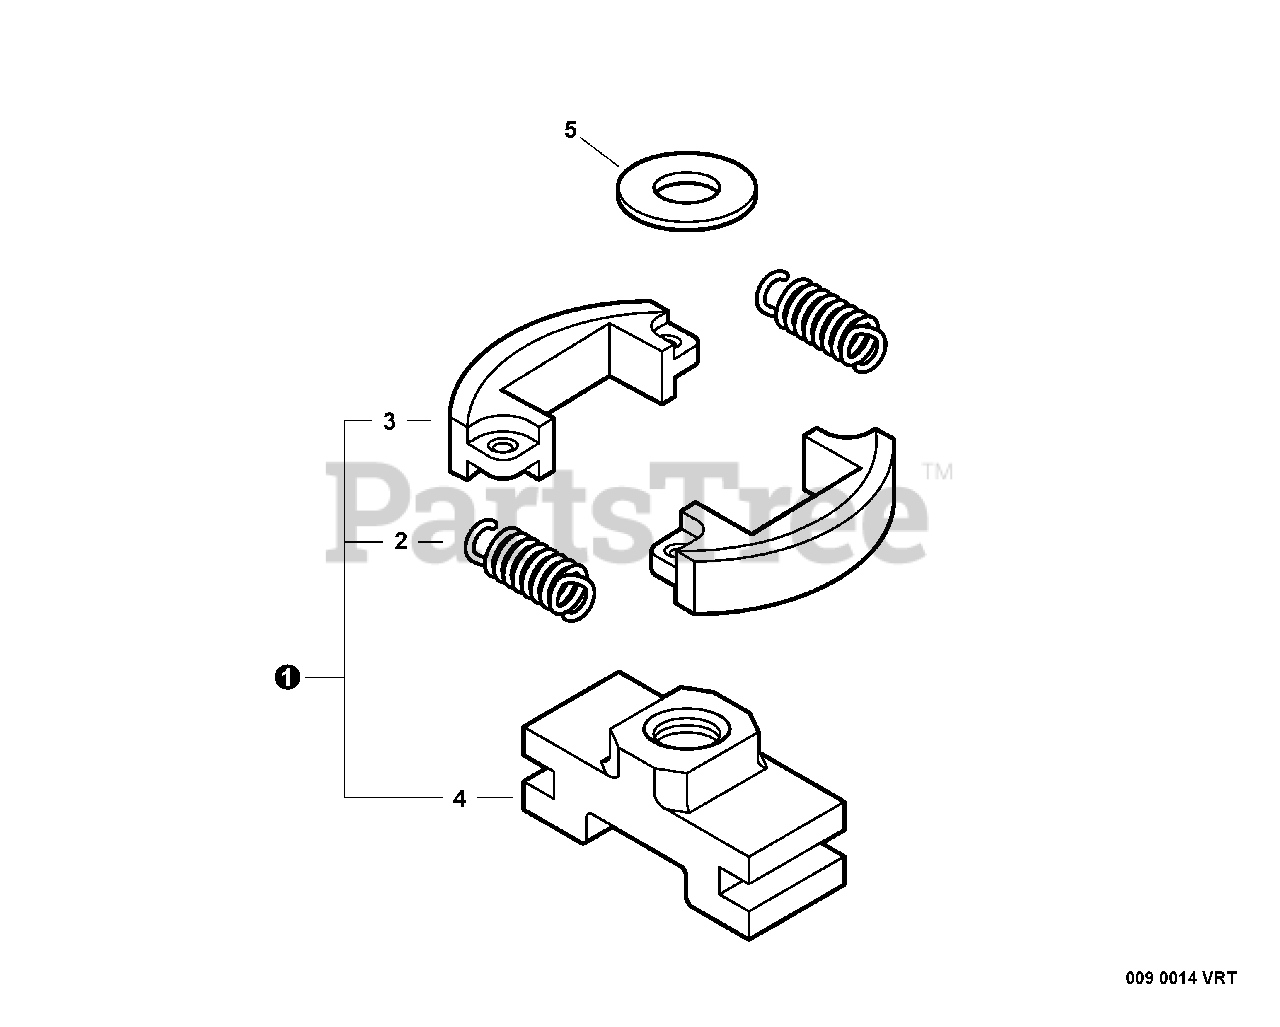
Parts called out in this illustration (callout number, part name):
1	CLUTCH ASSY
2	SPRING, CLUTCH
3	SHOE, CLUTCH
4	HUB, CLUTCH
5	WASHER 8
